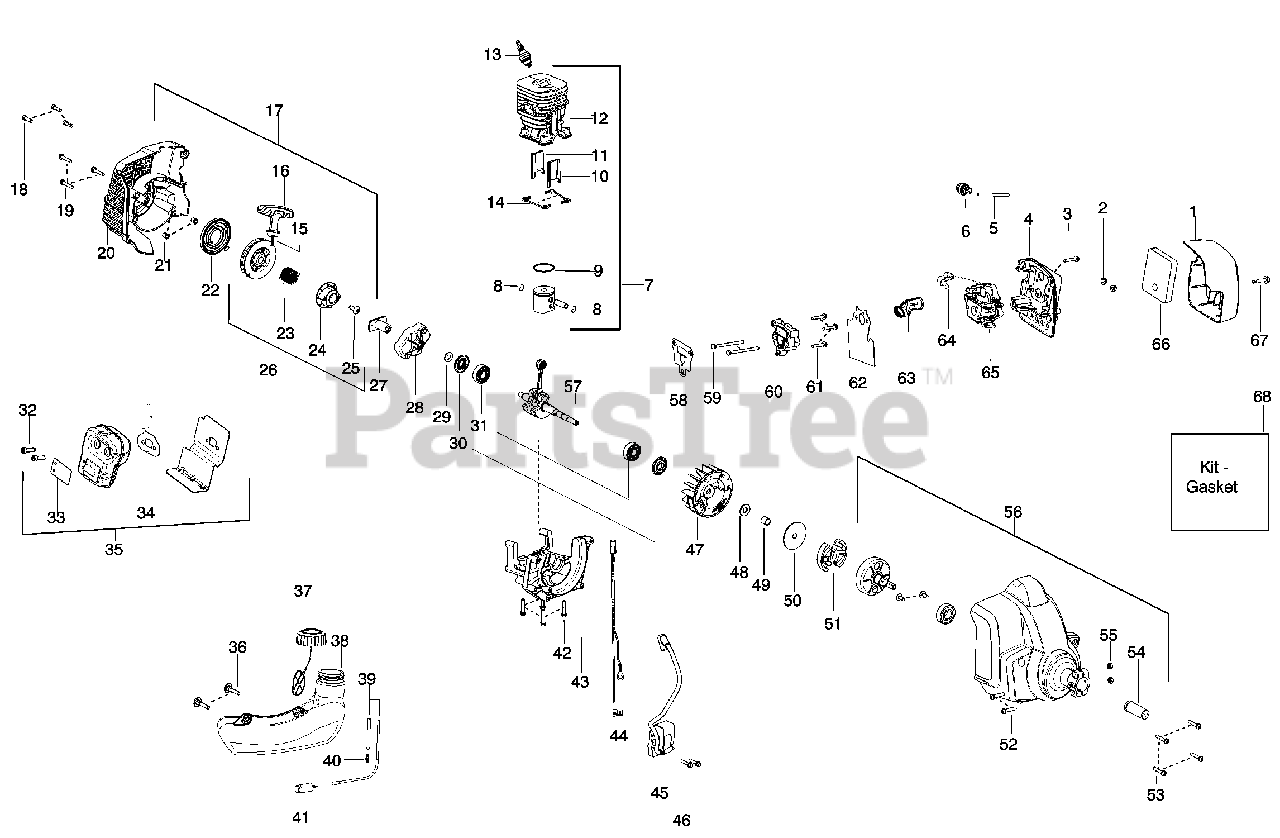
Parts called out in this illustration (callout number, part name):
1	Cover - Airbox
2	Nut - Carb. Screw
3	Screw 8-32
4	Base - Airbox
5	Fuel line - Purge Bulb
6	Assy - Purge Bulb
7	Kit - Piston/Cylinder
8	Retainer - Piston pin
9	Ring - Piston
10	Insert - Front Transfer Port
11	Insert - Rear Transfer Port
12	Cylinder - Machined
13	Spark Plug
14	Seal - Cylinder
15	Kit - Rope
16	Handle - Starter
17	Assy - Starter/Shroud
18	Screw M4 x 1.75
19	Screw m5x25mm
20	Assy - Starter Hsg. w/eyelet
22	Kit - Starter Spring
23	Spring - Starter Hub
24	Hub - Starter
25	Screw m6
26	Kit - Starter Pulley
27	Coupling - Starter
28	Assy - Starter Cup
29	Washer - Flat
30	Seal - Crankshaft
31	Bearing - Crankshaft
32	Bolt - Muffler
33	Kit - Spark Arrestor
34	Gasket - Muffler
35	Assy - Muffler
36	Screw - Tank Retainer
37	Assy - Fuel Cap w/ret.
38	Assy - Tank
39	Kit - Fuel line
40	Fitting - Fuel Line
41	Assy - Fuel Pickup
42	Screw - m5x25mm
43	Crankcase
44	Assy - Leadwire
45	Module - Ignition
46	Screw 8-32
47	Flywheel
49	Spacer - Flywheel
50	Washer - Clutch
51	Kit - Clutch Assy.
52	Screw 10-24 x 1"
53	Screw M5 x 25mm
54	Guide - Clutch Drum
55	Locknut 10-24
56	Assy - Fan Housing
57	Kit - Crankshaft Assy.
58	Gasket - Adapter/Cyl.
59	Bolt M5 x .80
60	Adaptor - Carburetor
61	Screw .20 x 32
62	Gasket - Carb./Adapter
63	Boot - Carb.
64	Lever - Choke
65	Kit - Carburetor
66	Filter - Air
67	Bolt - Knob
68	Kit - Gasket
